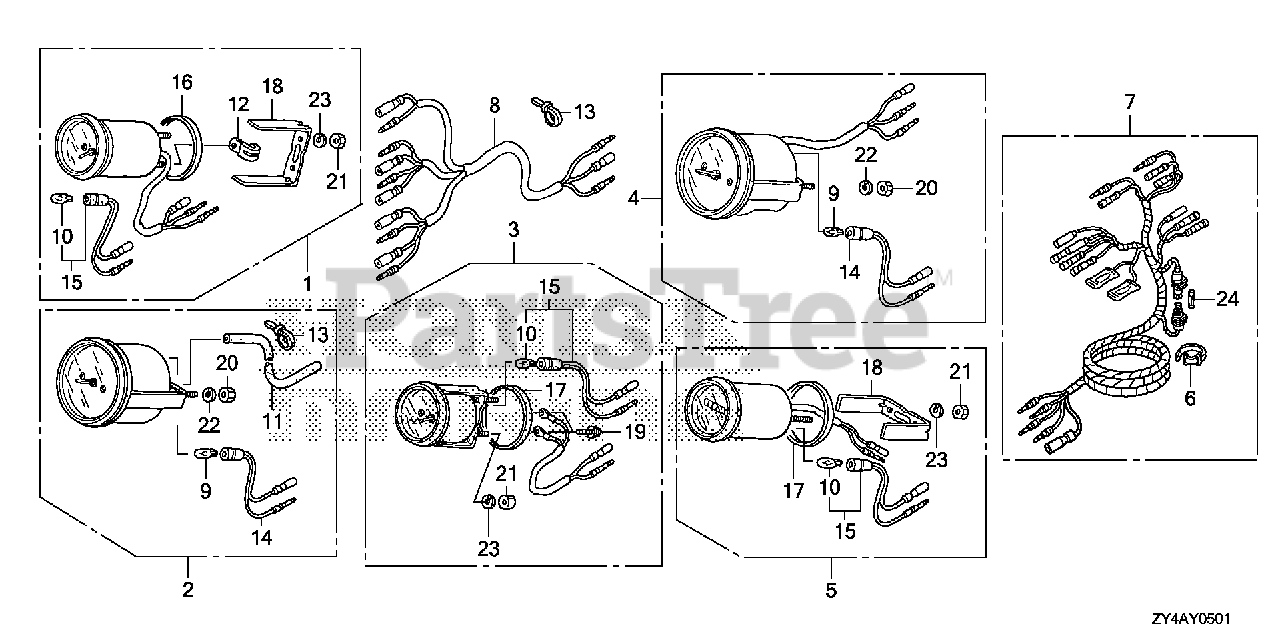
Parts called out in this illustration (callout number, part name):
1	METER KIT, TRIM
1	METER KIT, TRIM (B)
2	SPEEDOMETER KIT
2	SPEEDOMETER KIT (B)
3	METER KIT, VOLT
3	METER KIT, VOLT (B)
4	METER KIT, TACHO
4	METER KIT, TACHO (B)
5	METER KIT, HOUR (NA USE ALT:39700-ZW5-000ZA)
5	METER KIT, HOUR (B) (NA USE ALT:39700-ZW5-000ZA)
6	BAND B1, WIRE
7	HARNESS ASSY., METER (A)
8	HARNESS ASSY., METER (B)
9	BULB, WEDGE BASE (T10) (12V 1.7W) (STANLEY)
10	BULB, WEDGE BASE (12V 1.7W)
11	TUBE, SPEED METER (4X7X8000)
12	CLAMP
13	BAND, SELF-LOCK
14	SOCKET
15	SOCKET
16	GASKET
17	GASKET
18	BRACKET
19	SCREW-WASHER (3X22)
20	NUT, HEX. (5MM)
21	NUT, HEX. (4MM)
22	WASHER, SPRING (5MM)
23	WASHER, SPRING (4MM)
24	FUSE A (10A)
